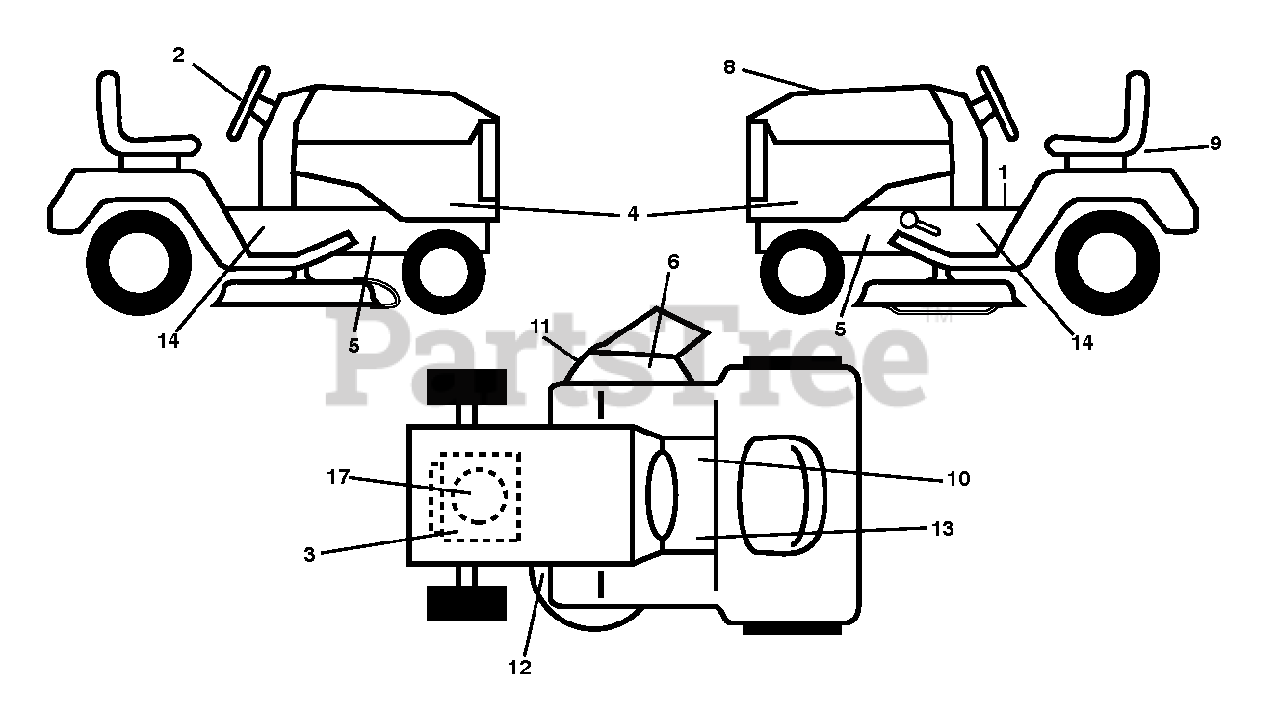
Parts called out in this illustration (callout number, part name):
6	DECAL, DECK DEFLECTOR, WARNING
9	DECAL BTRY SYMBOLS
11	DECAL.WARN.DFLCTRCTF
12	DECAL.V.BELT.30
